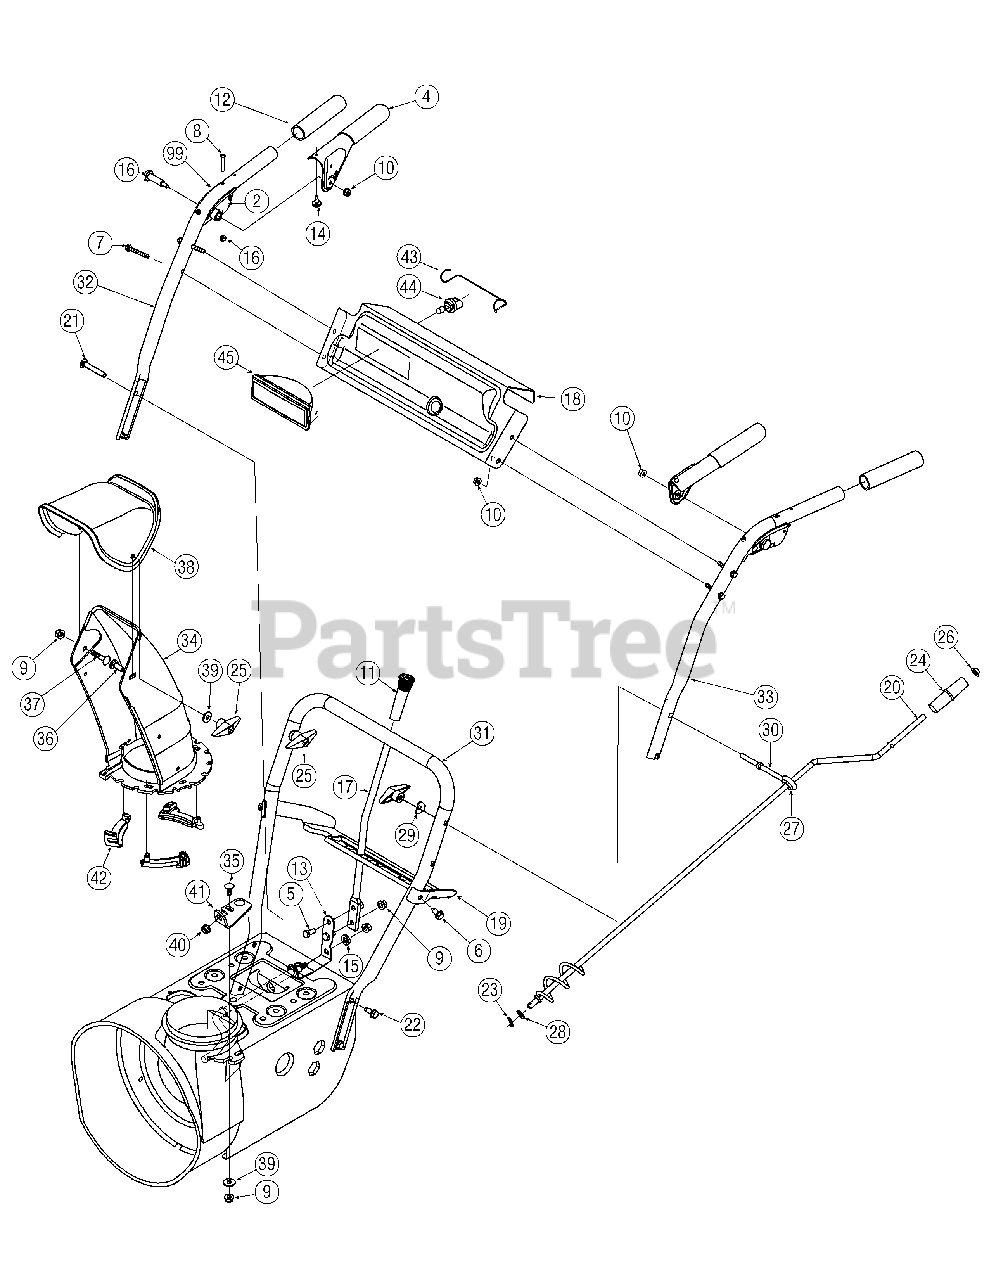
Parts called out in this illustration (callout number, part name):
1	Handle Ass’y, Lock, LH
2	Handle Ass’y, Lock, RH
3	Handle Ass’y, Engagement, LH
4	Handle Ass’y, Engagement, RH
5	Screw, Self-tapping, 5/16-18, .625
6	Screw, Self-tapping, 5/16-18, 1.0
7	Screw, Self-tapping, 1/4-20, 1.50
8	Screw, Machine, #10-24, 1.375
9	Nut, Flange Lock, 5/16-18, Nylon
10	Nut, Flange Lock, 1/4-20, Nylon
11	Grip, 0.5 ID x 3.45
12	Grip, 1.0 ID x 5.0
13	Spring Lever, Shift
14	Bumper, Rubber, .62 OD x .22
15	Washer, Flat, .350 sq. x .72 x .134
16	Screw, Shoulder, 1/4-20, .437
21	Screw, Carriage, 5/16-18, 2.25
22	Screw, 5/16-18, 0.75, Gr5
23	Pin, Cotter, .072 x 1.13
24	Crank Knob, 1.0 Dia. x 3.2 Black
25	Knob Assembly, Wing Nut, 5/16-18
26	Cap, Push, 3/8 Rod
27	Grommet, .44 ID x .94 OD x.50
28	Washer, Flat, .375 x .738 x.063
29	Washer, Saddle, 320 x .93 x .060
30	Eye Bolt, Chute Crank
34	Chute, Lower, 5.0 Diameter
35	Bolt, Carriage, 5/16-18, 1.0
36	Bolt, Carriage, 5/16-18, 1.0
37	Bolt, Carriage, 5/16-18, .750
38	Chute, Upper, w/ Label
39	Washer .349 ID x .879 OD x .063
40	Bushing, Plastic, .380
42	Chute, Flange Keeper
43	Retainer, Lens
44	Lamp, Halogen, 12V, 27W
45	Lens Assembly, Lamp
46	Wire Harness, Lamp
